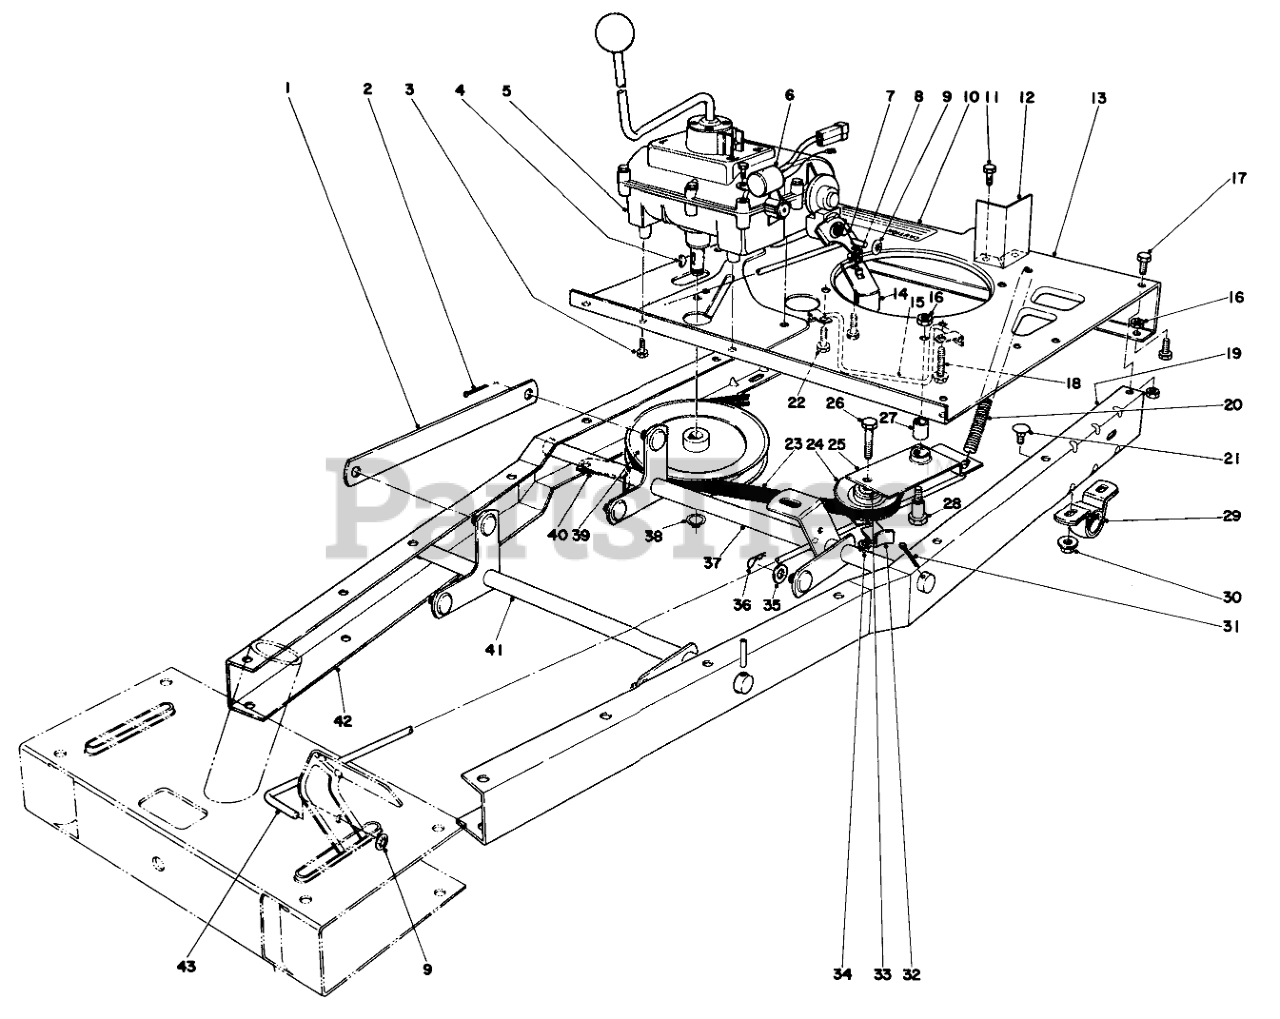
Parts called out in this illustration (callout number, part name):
1	Linkage-Height Adj.
2	PIN-COTTER
3	5/16-18 X 5/8 SEMS SC
4	KEY-WOODRUFF
5	Transmission
6	Control Module
7	Brake Return Spring
8	WASHER-PLAIN
9	PUSH ON SPEED NUT 1/4
10	Decal
11	SCREW-HH
12	Baffle-Carb
13	Engine Mounting Plate
14	Belt Retainer
15	Belt Guide
16	NUT-LOCK, CONE
17	SCREW-HH
18	SCREW-HWHTF
19	Frame Chanel, L.H.
20	Clutch Tension Spring
21	SCREW-CARR
22	Sems Screw
23	V-BELT
24	PULLEY-IDLER
25	Traction Idler (Incl. Ref. #27)
26	SCREW-HH
27	BUSHING
28	CLUTCH PIVOT BOLT
29	PILLOW BLOCK
30	NUT-HF
31	PIN-COTTER
32	RETAINER-BELT
33	Washer
34	NUT-LOCK, CONE
35	WASHER-FLAT
36	PIN-COTTER
37	Height Adjustment
38	RING-SNAP, EXTERNAL
39	PULLEY
40	TRANS BELT RET B
41	FRONT LIFT WA B
42	Frame Channel R.H.
43	CLUTCH ROD
